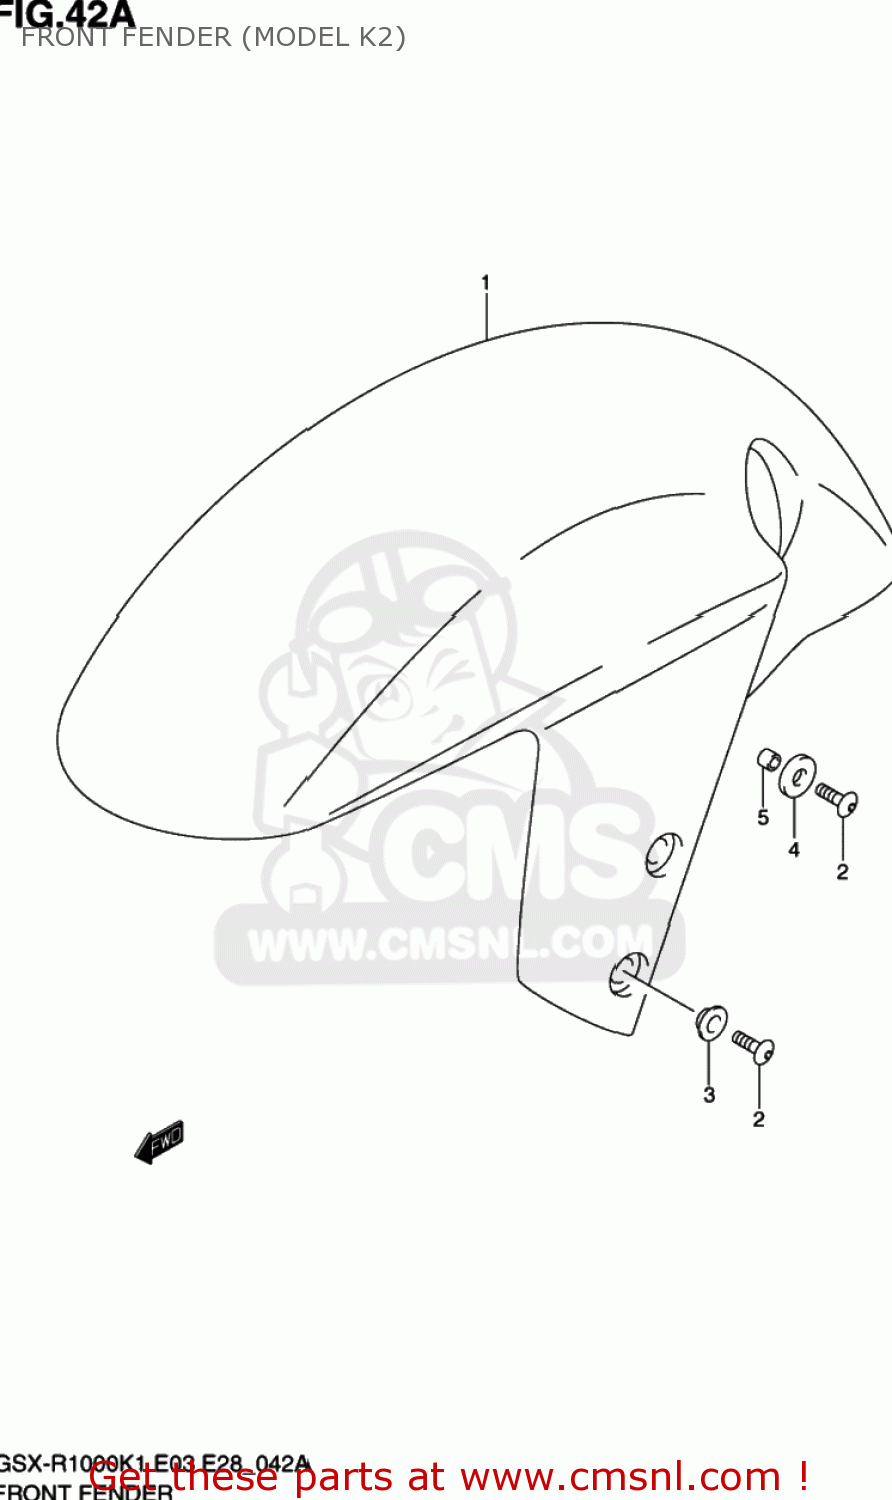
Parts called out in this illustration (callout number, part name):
1	FENDER,FR
2	SCREW(6X16)
3	WASHER(6.3X16X1.5)
4	WASHER,FR FENDER FR NO.2
5	SPACER(6.5X9X6.7)
